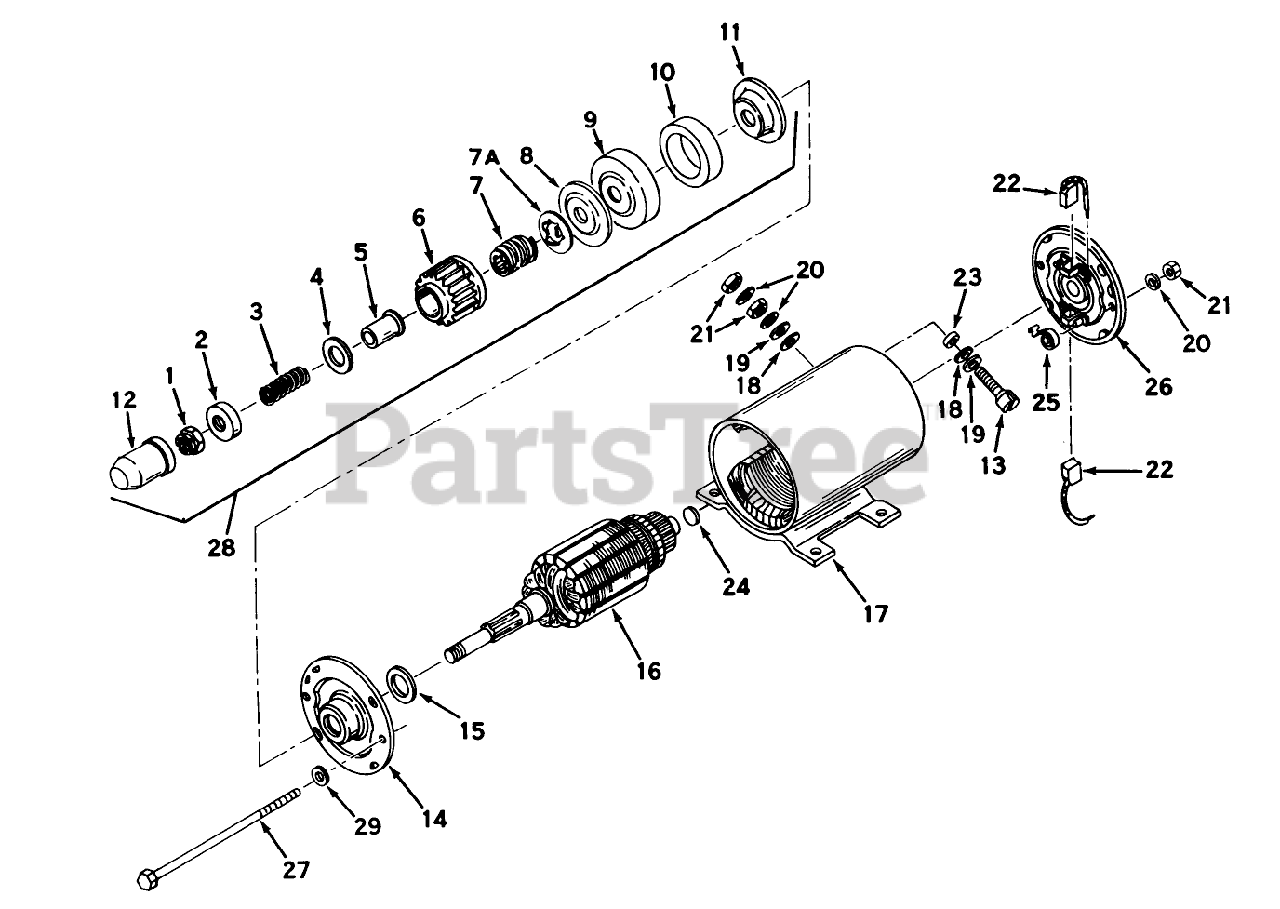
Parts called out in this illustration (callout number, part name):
1	Nut, Hex
2	Setscrew
3	Spring, Anti-Drift
4	Washer, Pinion
5	Sleeve, Anti drift
6	Gear, Pinion
7	Shaft, Screw
7A	Stopper, Screw
8	Washer, Thrust
9	Cap, Cushion
10	Cushion, Rubber
11	Washer, Thrust
13	Bolt, Terminal
14	Cap Assy., Drive end (Incl. Bearing)
15	Washer, Spacing (.024 Thick)
15	Washer, Spacing (.008 Thick)
16	Armature
17	Housing Assy. (Incl. pole shoes, field coils, terminal post, straight mounting bracket, Nos. 18 thru 21)
18	Washer, Insulating
19	Washer
20	Washer, Lock
21	61710/VAR.HILLER AT
22	Brush Spring Kit
23	Bushing, Insulating
24	Washer, Spring
25	Spring, Brush
26	End Cap Assy., Commutator
27	Bolt, Thru
28	Drive Assy., Complete (Incl. Nos. 1 thru 12)
29	Washer
